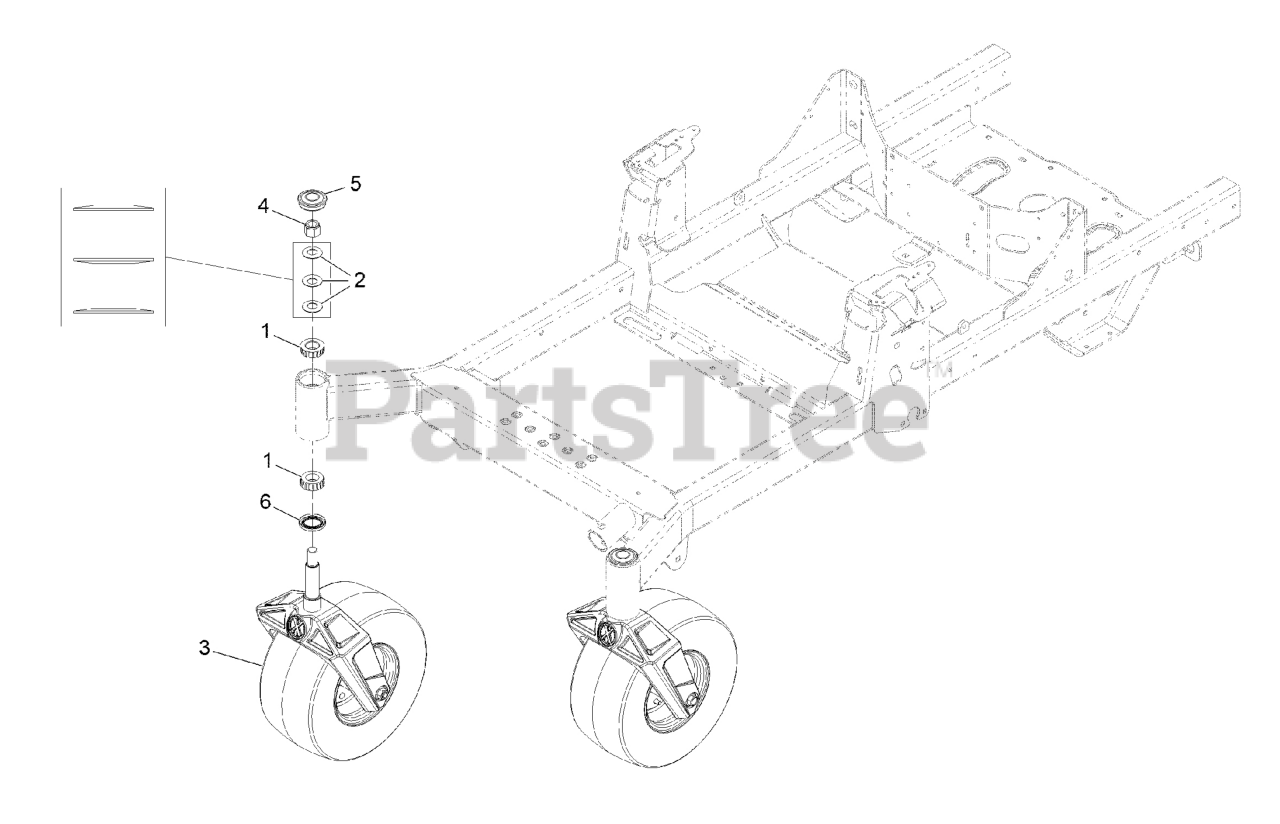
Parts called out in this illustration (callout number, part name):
1	Cone-Bearing Tapered Roller
2	WASHER-BELLVILLE
3	ASM-Front Castor W/Fork
4	NUT-LOCK, NI
5	CAP, GREASE
6	SEAL-GREASE
